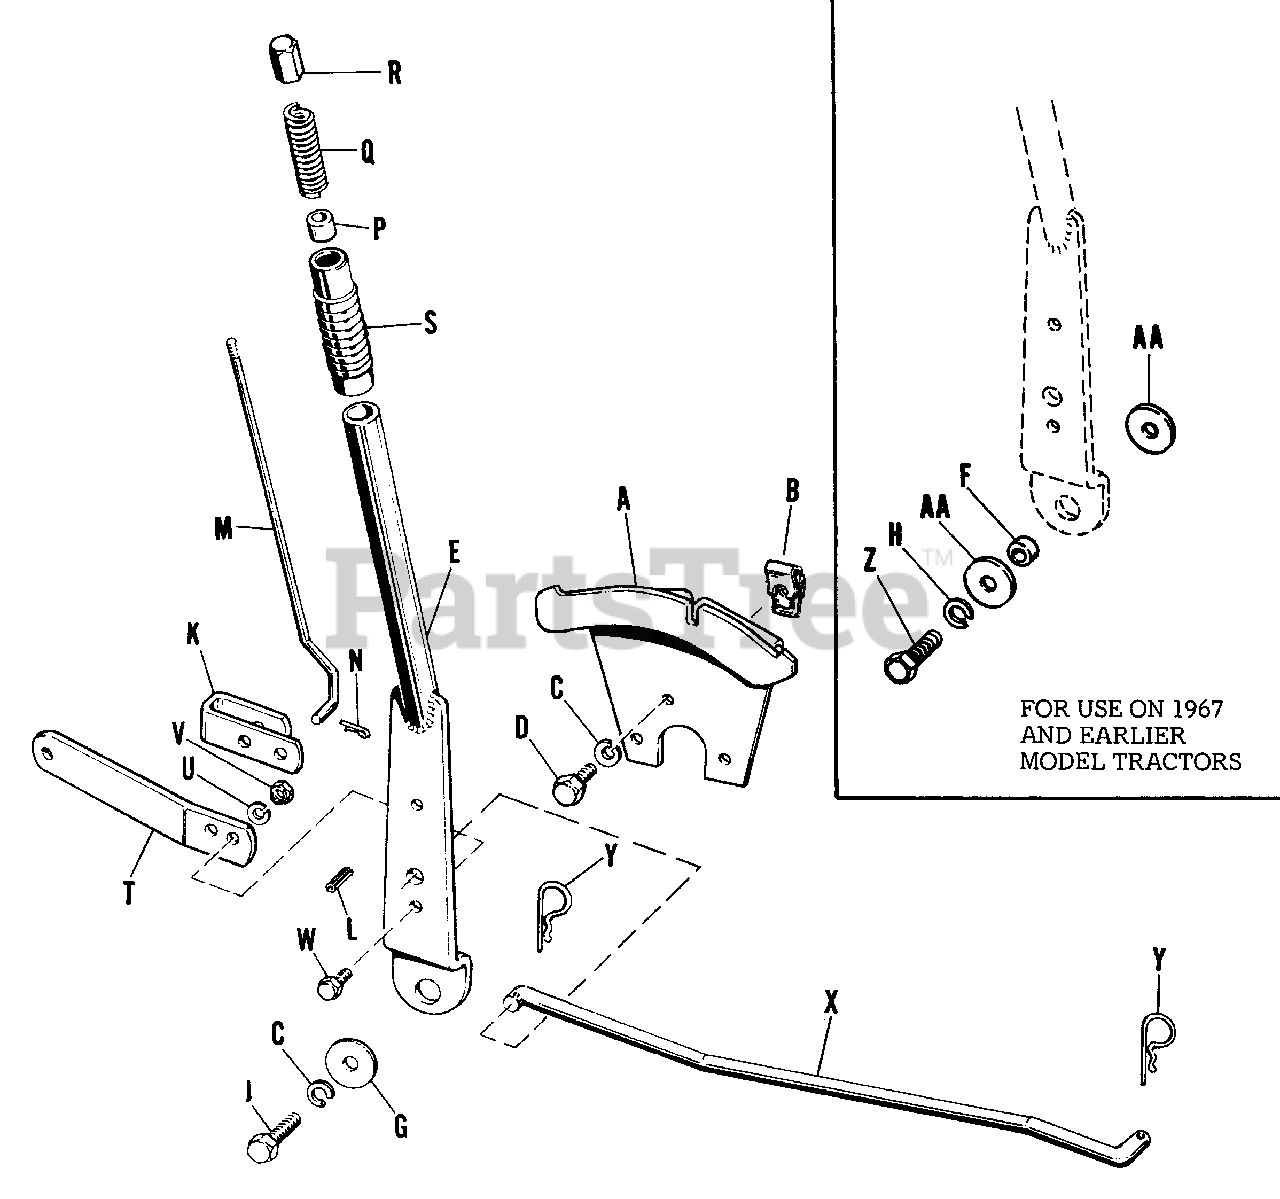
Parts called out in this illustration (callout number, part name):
A	Quadrant Assembly, R.H.
B	Nut Retainer
C	Lock Washer, 5/16"
D	Capscrew, Hex. 5/16"-18 x 3/4" lg., SAE Grade 5
E	Lift Lever Assembly, R.H.
F	Spacer
G	Washer, Plain, 5/16"
H	Lock Washer, 7/16"
J	Hex Capscrew, 5/16"-18 x 5/8" lg.
K	Lift Lever Latch
L	Roll Pin, 3/8" x 1"
M	Latch Rod, R.H.
N	Cotter Pin, 3/32" x 3/4" lg.
R	Thumb Button
S	Handle Grip
T	Lift Lever
U	Lock Washer, 3/8"
V	Hex Nut, Full, 3/8"-16
W	Hex Capscrew, 3/8"-16 x 7/8" lg.
X	Front Lift Rod
Y	Spring Clip
Z	Hex Capscrew, 7/16"-14 x 1 1/2" lg.
AA	Washers, Plain, 7/16"
